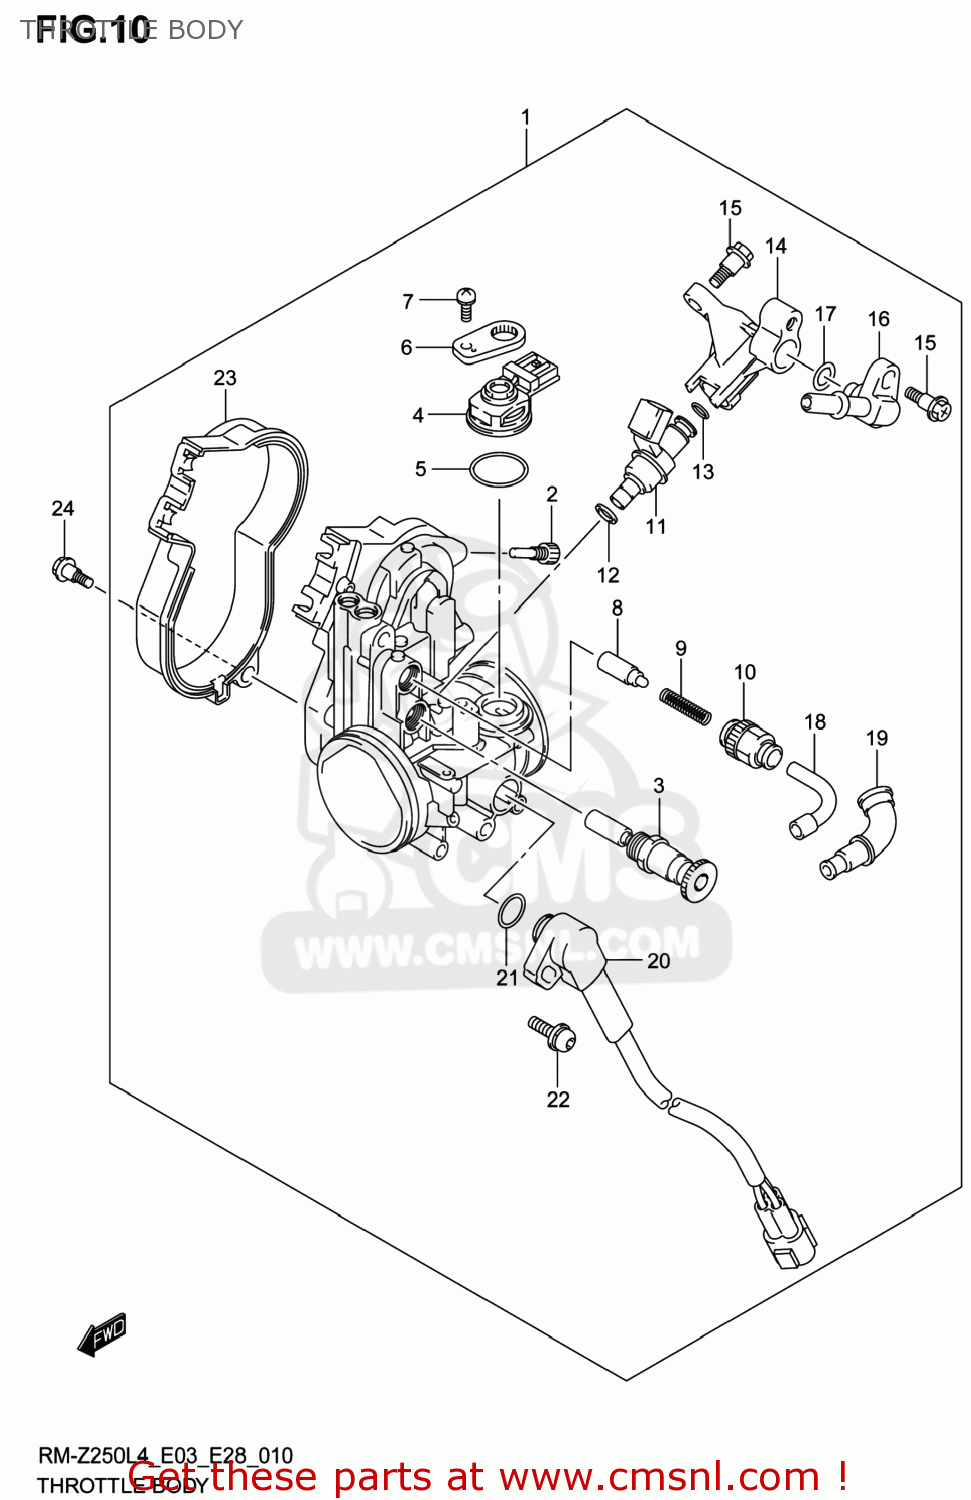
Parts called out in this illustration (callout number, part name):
1	BODY ASSY,THROTTLE
2	SCREW
3	STARTER
4	SENSOR,MAP
5	O RING
6	PLATE,STAY
7	SCREW
8	VALVE,STARTER
9	SPRING
10	HOLDER,CABLE
11	INJECTOR ASSY
12	RING,SEAL
13	O RING
14	PIPE,FUEL
15	SCREW
16	JOINT
17	O RING
18	GUIDE,CABLE
19	CAP
20	SENSOR ASSY,THROTTLE
21	O RING
22	SCREW
23	COVER,THROTTLE
24	SCREW
